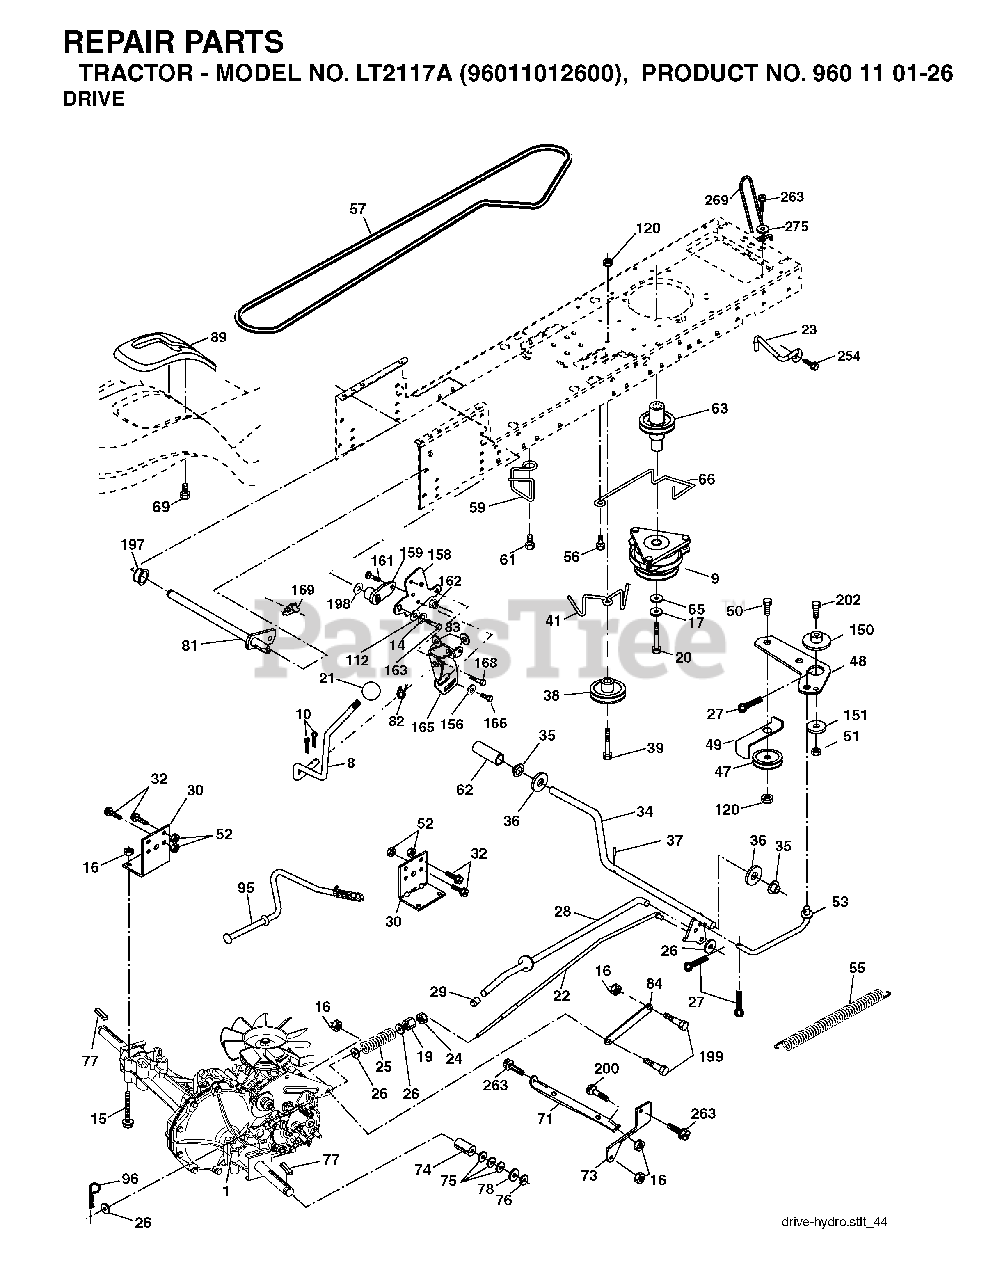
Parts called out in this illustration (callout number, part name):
8	ROD.SHIFT.FENDER.ADJ.STLT
10	PIN COTTER
14	LOCKWASHER
15	BOLT HEX 5/16-18 GR 5
16	NUT.71038.31-18.HEX.NYLOCK
19	NUT
20	BOLT HEX 7/16-20X4-1/4"
21	PISTOL KNOB
22	ROD BRAKE HYDRO
23	BRACKET, ANTI-ROTATION
24	NUT
25	SPRING ROD LT
27	COTTER PIN
28	ROD, PARKING BRAKE
29	PLUNGER CAP
30	BRKT, TRNSXLE MNT 20"
32	BOLT
34	SHAFT, FOOT PEDAL
35	BEARING.NYLON
36	WASHER LT
37	DRIVE PIN
38	PULLEY IDLER COMPOSITE
41	KEEPER, BELT IDLER
47	IDLER PULLEY
48	BELLCRANK, CLUTCH
49	RETAIN BELT
50	BOLT.3/8-16X1.50
51	LOCKNUT
52	LOCKNUT
53	LINK.CLUTCH.7.66.2005
55	SPRING, RETURN LT
56	SCREW.3/8-16
57	DRIVE BELT, LTH & YTH TRACTORS
59	KEEPER, BELT CENTER
61	SCREW 3/8-16X.875
62	PEDAL COVER T
63	PULLEY- ENGINE
65	LOCKWASHER
66	KEEPER BELT ENGINE
69	SCREW.HI-LO.CONSOLE
71	STRAP TORQUE LH HYDRO
73	STRAP TORQUE RH HYDRO
74	SPACER AXLE
76	E-RING LT
77	SQUARE KEY
81	SHAFT ASM CROSS TAPERED
82	SHIFT SPRING
83	WASHER
84	LINK TRANSAXLE
95	CONTROL ASM. BYPASS HYDRO
96	RETAINER M
112	WASHER LT
120	NUT LOCK FLG 3/8-16 UNC
150	SPACER, RETAINER
151	WASHER 12/32X2X10GA
156	WASHER.SRRTD.5/16
158	BRACKET
159	HUB.SHIFT
161	BOLT
162	NUT.CROWNLOCK.1/4
163	BOLT
165	RP BRACKET
166	SCREW
168	BOLT.SHOULDER.5/16-18X
169	PLATE.FASTENING.CROSS.SHAFT
197	NYLINER SNAP 5/8" ID
198	WASHER.NYL.7/8IDX.105"HYD CR
199	BOLT SHOULDER 5/16-18 UNC
200	BOLT
202	BOLT.3/8-16X1.50
254	SCREW 3/8-16X1
263	SCREW, 3/8-16X3/4
275	WASHER
